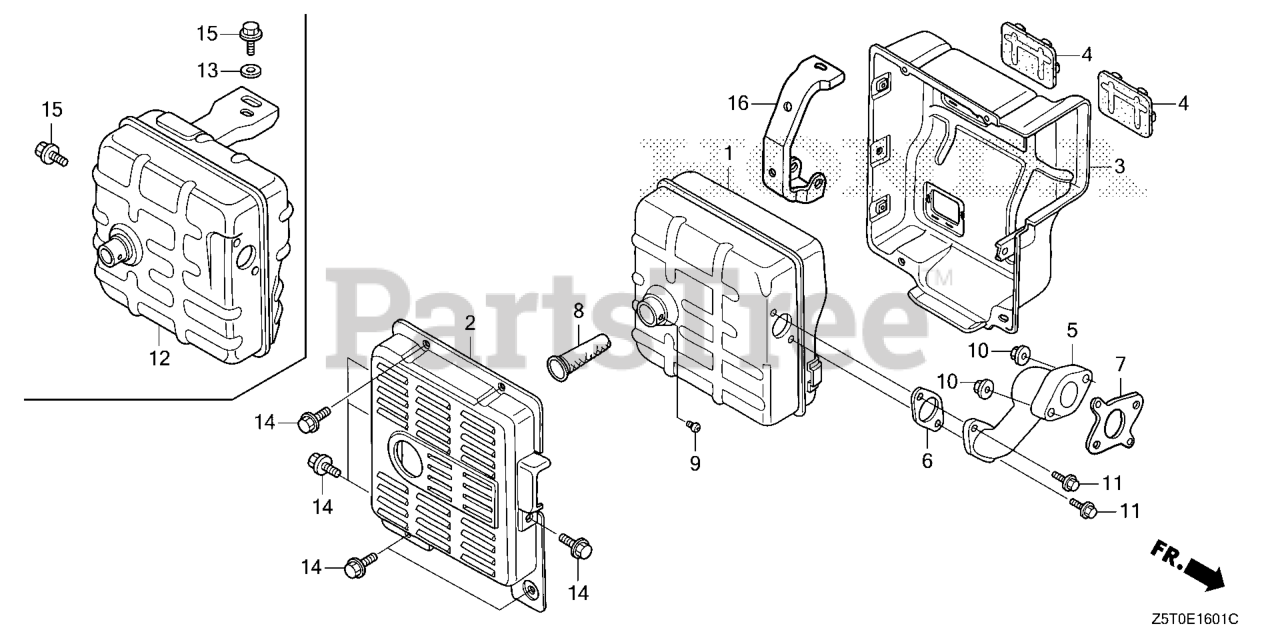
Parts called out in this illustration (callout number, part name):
2	PROTECTOR, MUFFLER (OUTER)
3	PROTECTOR, MUFFLER (INNER)
4	SEAL, MUFFLER PROTECTOR
6	GASKET, EX. PIPE
7	GASKET, EX. PIPE
8	ARRESTER, SPARK
9	SCREW, TAPPING (4X8)
10	NUT, FLANGE (8MM)
11	BOLT, FLANGE (8X20) Use up to Engine SN 1609606.
12	MUFFLER (DENYO)
14	BOLT, FLANGE (6X10)
